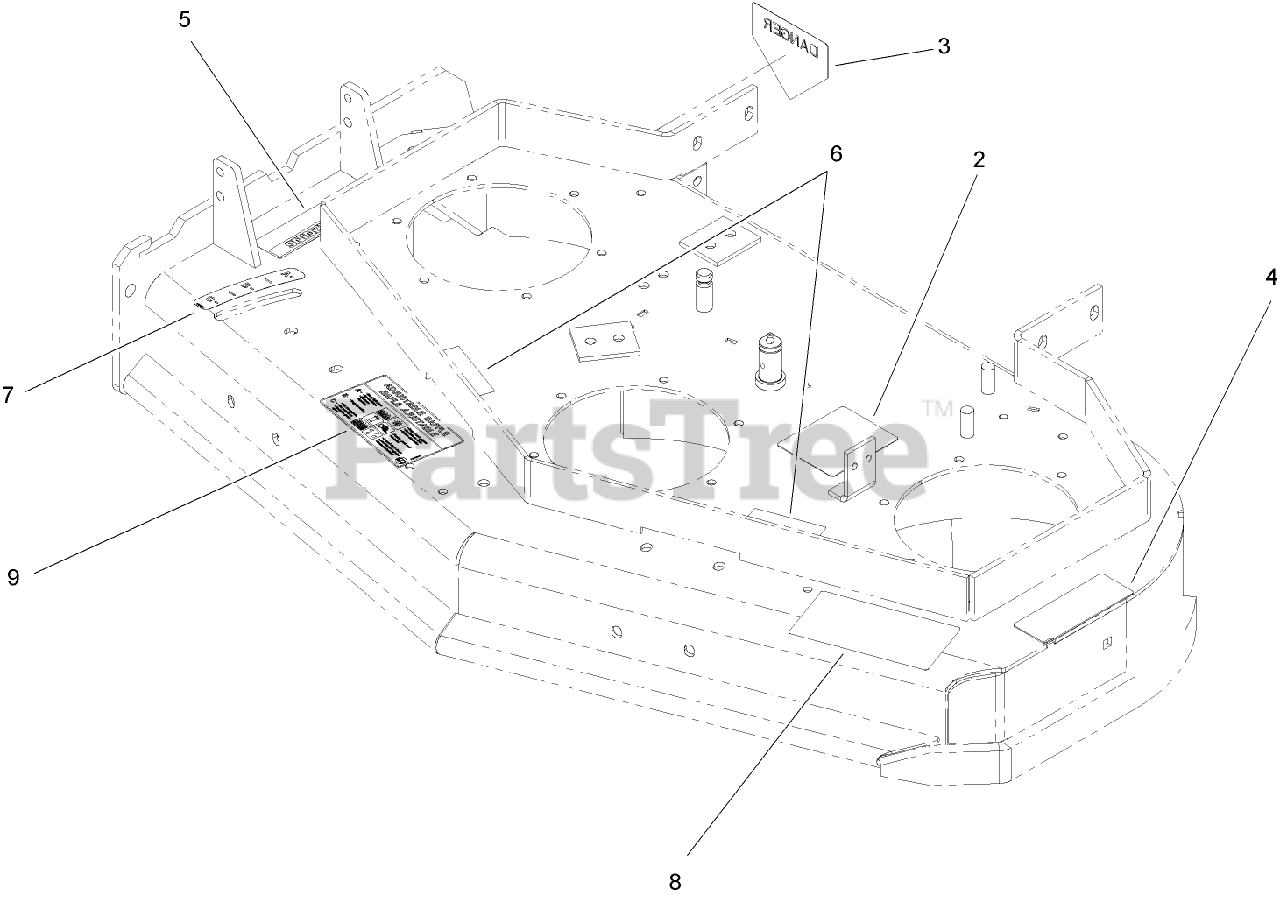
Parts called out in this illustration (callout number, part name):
2	DECAL-ROUTING, BELT
3	DECAL-DANGER
4	DECAL-TORQUE, BOLT
5	DECAL-WARNING
6	DECAL-COVER, MISSING
7	DECAL-SETTING, BAFFLE
8	DECAL-DANGER, THROWN OBJECT
9	DECAL-ADJUSTMENT, BAFFLE
